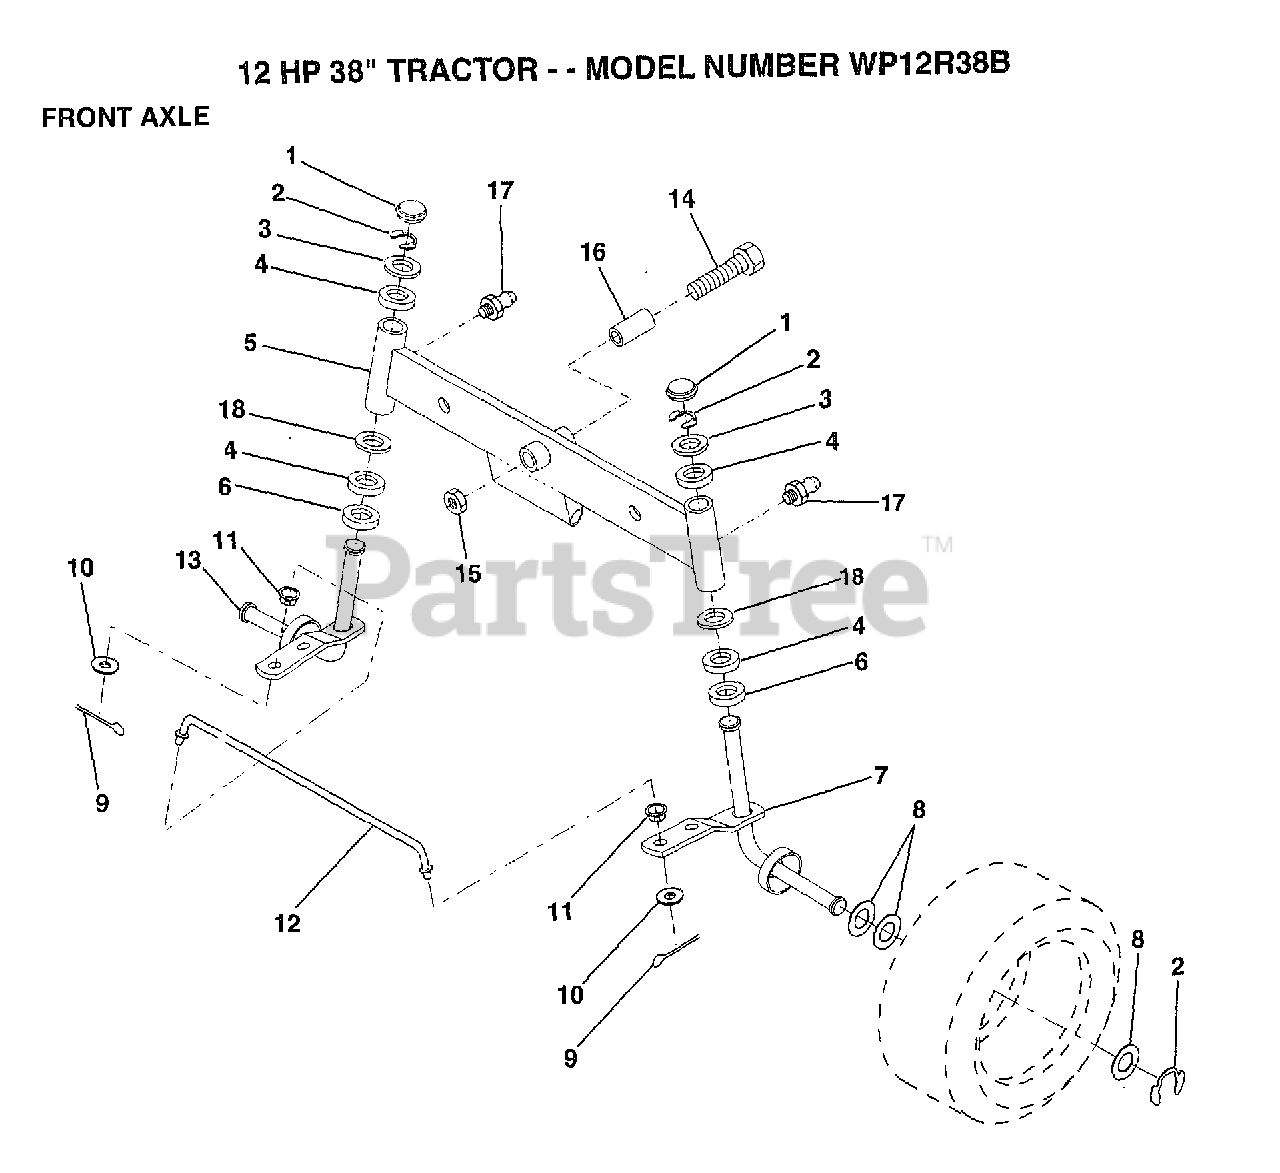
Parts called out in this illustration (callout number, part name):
1	CAP
2	RING
3	WASHER
4	COL. SRTG. BEAR.
6	WASHER .T
7	SPINDLE ASM RH
8	WASHER
9	COTTER PIN
10	WASHER
11	BUSHING.DRAGLINK
12	TIE ROD
13	SPINDLE ASM LH
14	BOLT HEX 5/8-11
15	"NUT-LOC,FLANGE LT"
16	BEARING
17	ZERK M
18	WASHER
